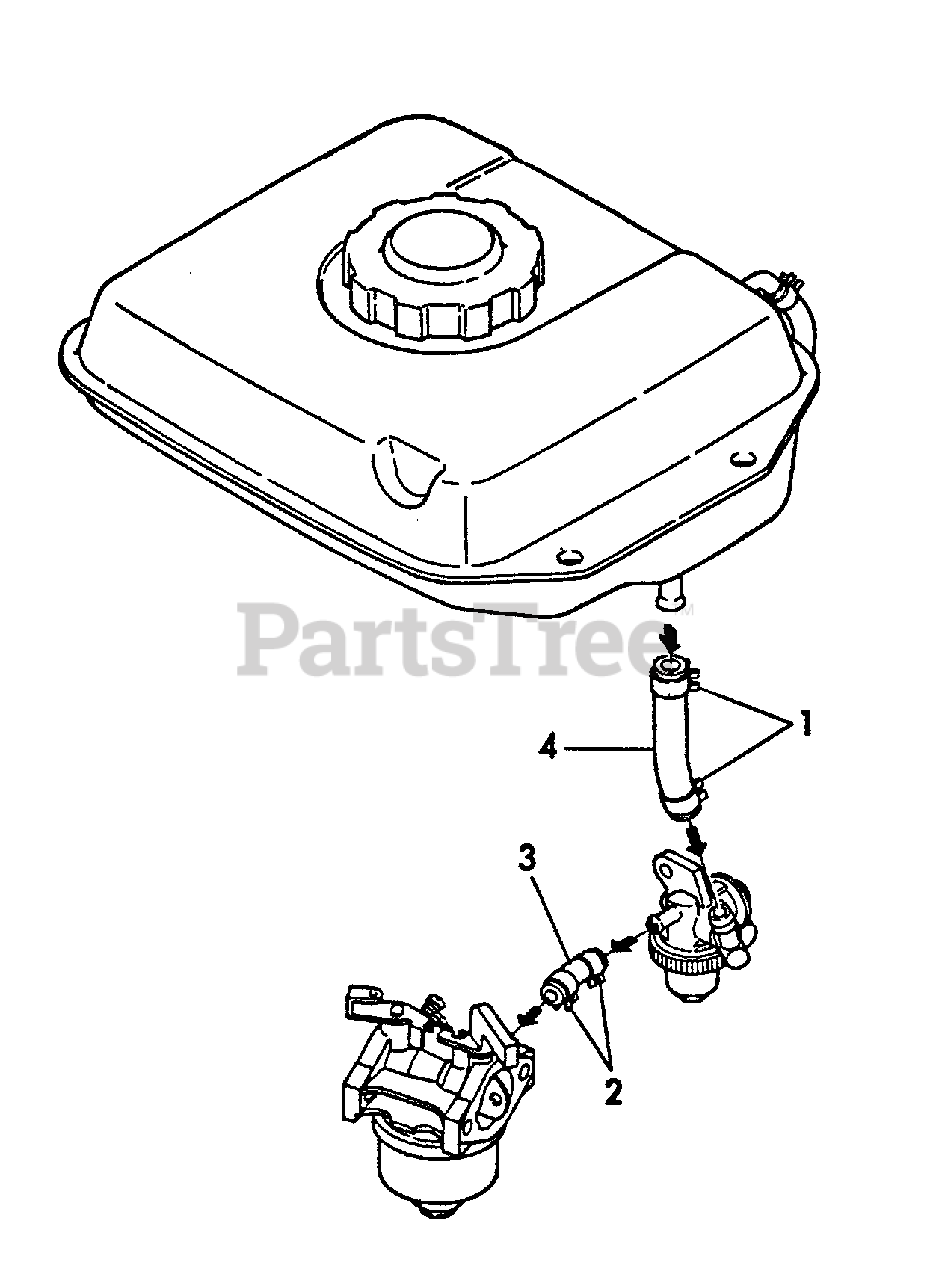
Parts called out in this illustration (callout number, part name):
1	CLAMP, HOSE
2	CLAMP, HOSE - 9
3	PIPE, FUEL
4	PIPE, FUEL
